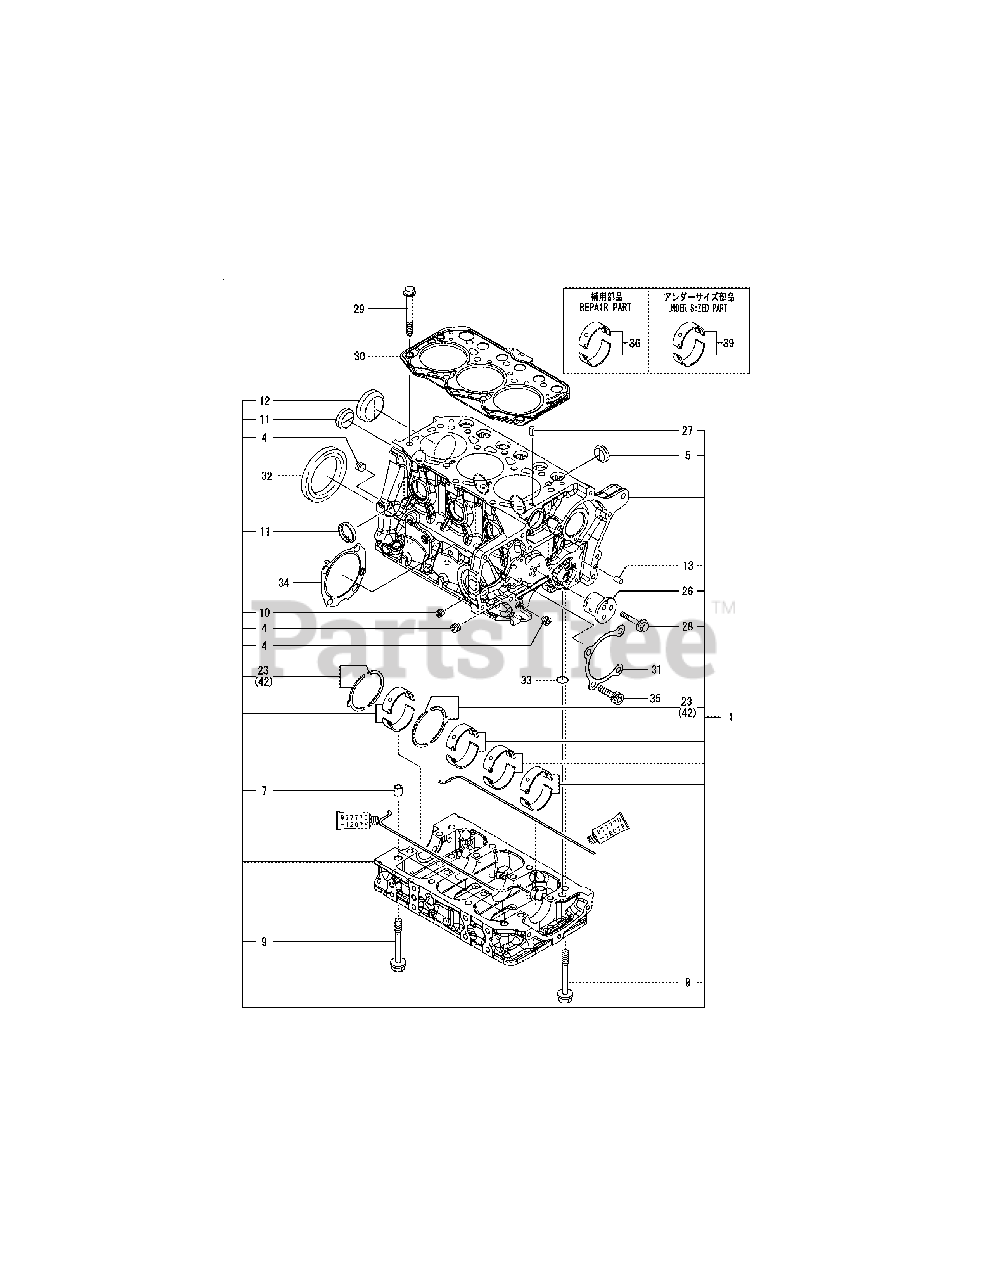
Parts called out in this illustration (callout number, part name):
1	BLOCK ASSY, CYLINDER
9	BOLT, METAL CAP
13	PARALLEL PIN, M6X10
23	METAL ASSY, THRUST
26	SHAFT, IDLE GEAR
27	SPRING PIN 6X12
28	BOLT M 6X 40 PLATED
29	BOLT, CYLINDER HEAD
30	GASKET, CYL.HEAD
31	GASKET, FOP BOLT
36	MAIN BEARING SET
39	MAIN METAL US=0.25
42	BEARING, THRUST .25OS
